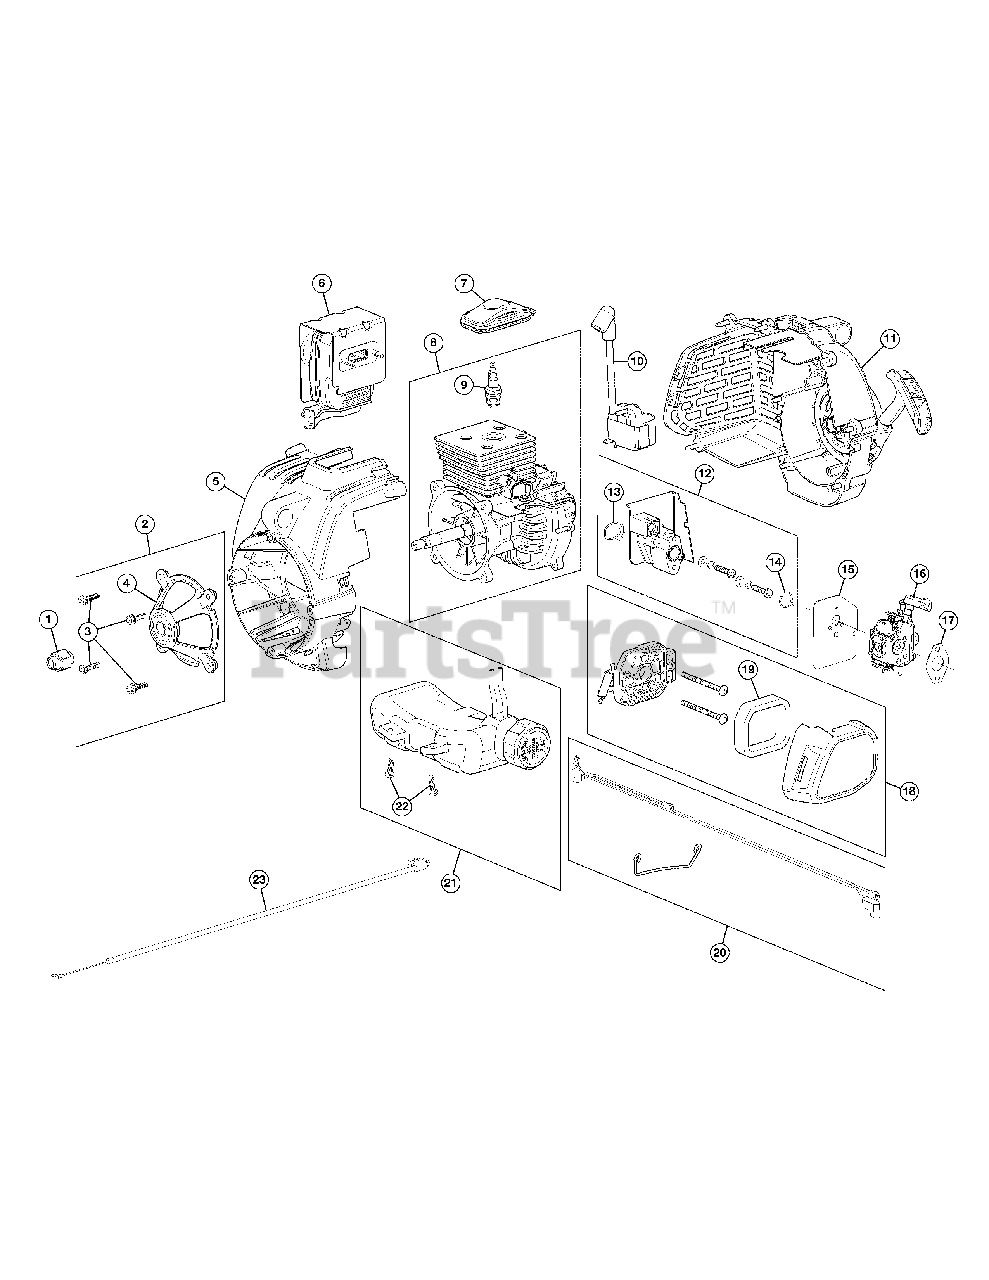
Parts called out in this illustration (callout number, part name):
2	Bearing Holder Assembly (Incl. 3 and 4)
4	Bearing Holder
5	Front Engine Cover Assembly
6	Muffler Assembly
7	Spark Plug Cover
8	Short Block Assembly (Incl. 9)
9	Spark Plug
10	Module Assembly
11	Rear Engine Cover Assembly
12	Insulator Assembly (Incl. 13 and 14)
13	Insulator O-Ring
14	Carburetor O-Ring
16	Carburetor
17	Carburetor Gasket
18	Air Cleaner Assembly
19	Air Cleaner Filter
20	Lead Wire Assembly
21	Fuel Tank Assembly (Incl. 22)
22	Screw (x2)
23	Throttle Cable
